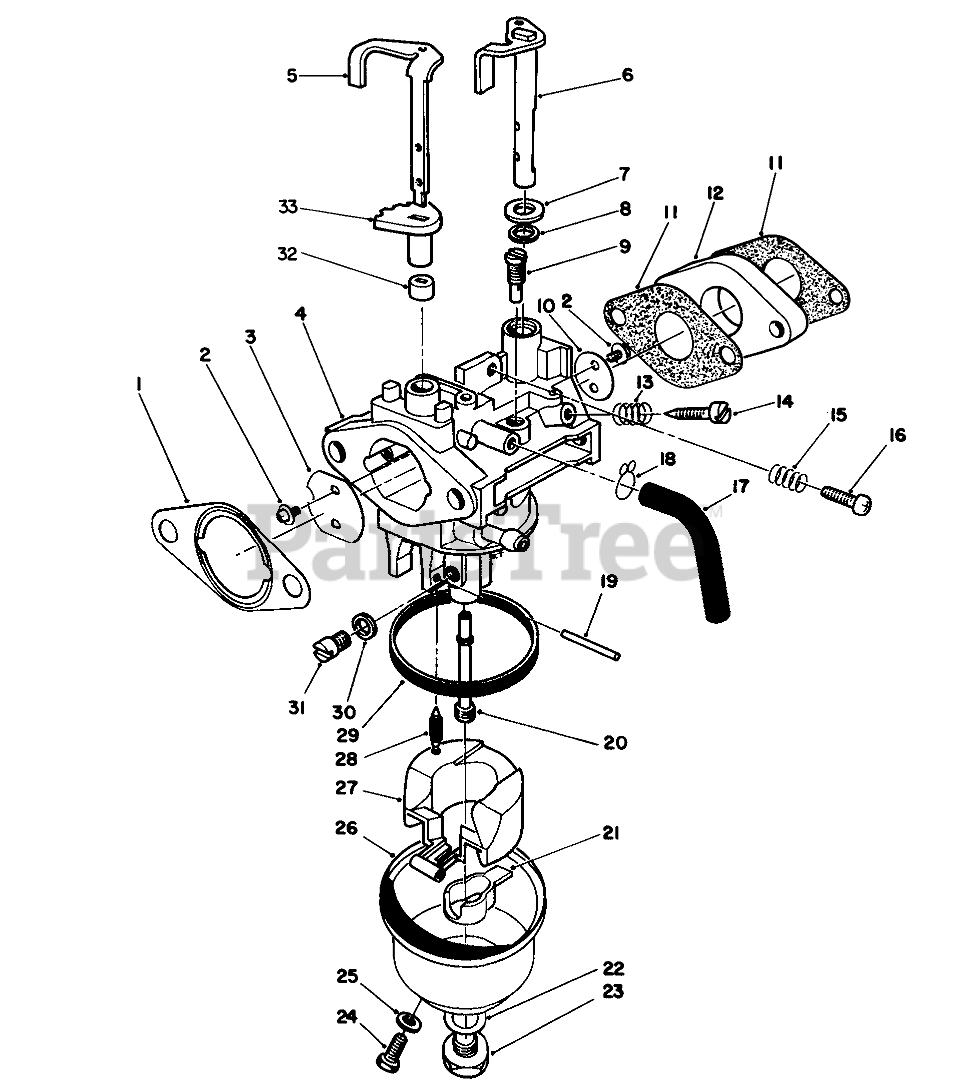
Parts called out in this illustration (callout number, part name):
1	GASKET F/W ENGINE
2	Screw
3	VALVE
4	Body-Carburetor
5	Shaft-Choke Valve
6	SHAFT
7	WASHER
8	Seal-Throttle Shaft
9	PILOT JET
10	VALVE
11	Gasket-Carburetor
12	CARB INSULATOR
13	SPRING-PILOT SCREW
14	ADJUSTER
15	Spring-Idle Stop
16	SCREW
18	CLAMP
19	Pin
20	NOZZLE
21	SPACER
22	GASKET
23	SCREW
24	SCREW
25	GASKET
27	FLOAT
28	NEEDLE
29	FLOAT BOWL GASKET
30	SPACER
31	MAIN JET
32	LOWER CHOKE RING
33	UPPER CHOKE RING
